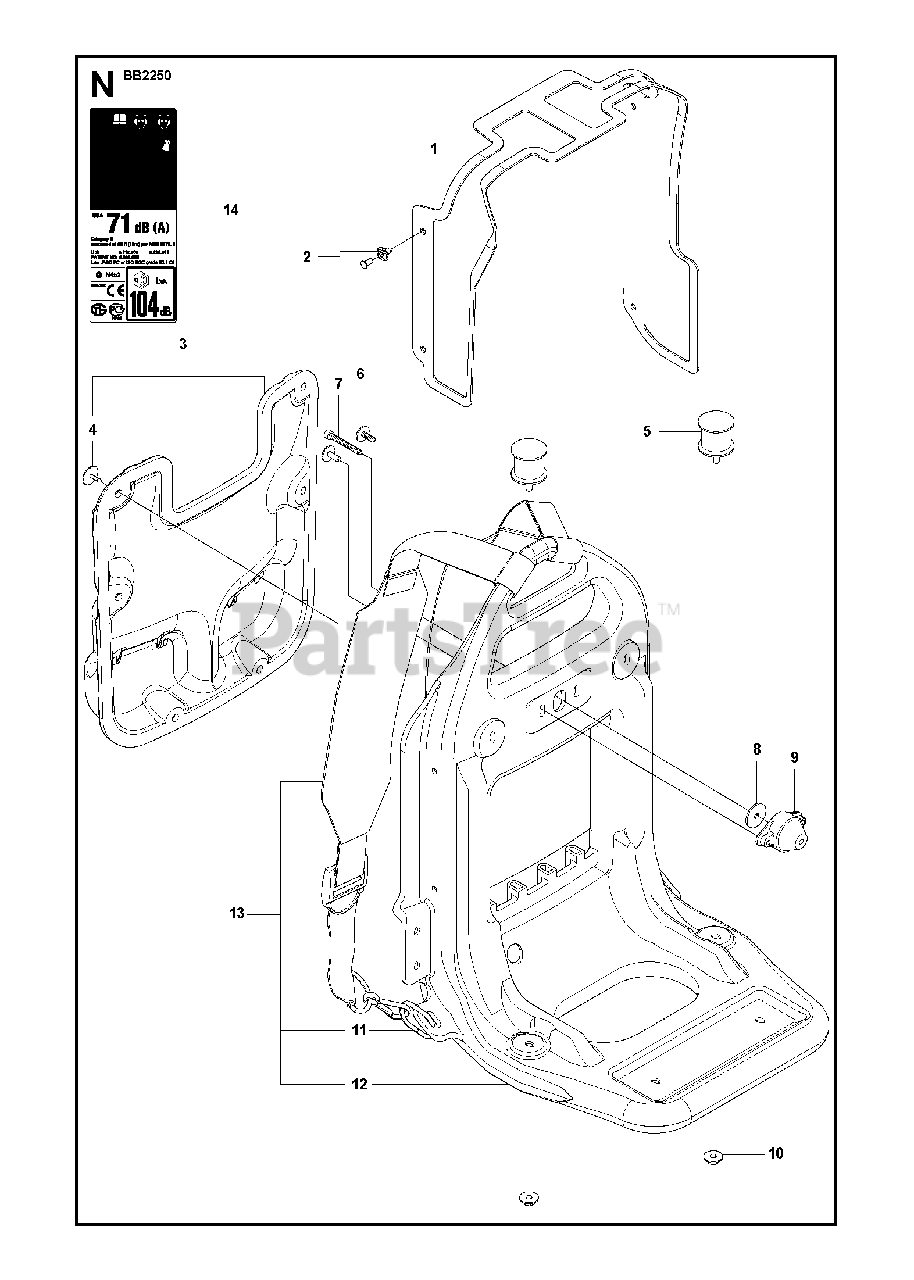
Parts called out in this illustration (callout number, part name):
2	CLIP
4	CLIP
5	DAMPER
8	WASHER
9	DAMPER
10	NUT (M6)
11	RING
13	FRAME ASSY
